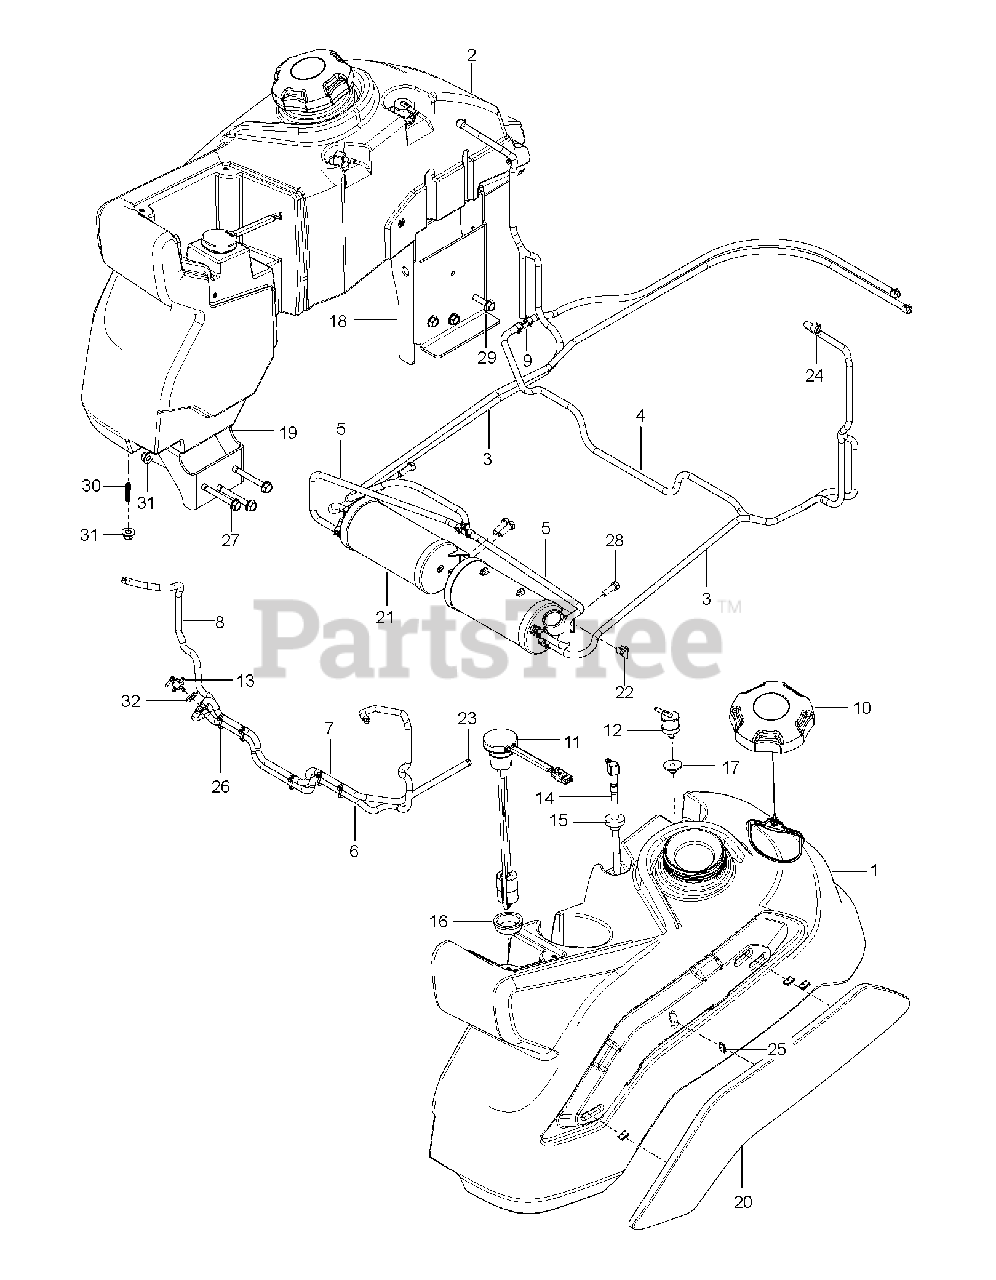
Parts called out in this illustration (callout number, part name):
1	FUEL.TANK.ASM.LH.PZ.REFRESH.18
2	FUEL.TANK.ASM.RH.PZ.REFRESH.18
3	HOSE.3/16".VAPOR.LINE.42"LGTH
4	HOSE.3/16".VAPOR.LINE.55"LGTH
5	HOSE 3/16" VAPOR LINE 13" LENG
6	HOSE.1/4".LOW.PERM.FUEL.LN.46"
7	Fuel Hose, 1/4" Low Perm
8	HOSE.1/4".LOW.PERM.FUEL.LN.24"
9	TEE, FUEL LINE 3/16"
10	CAP, FUEL
11	SENSOR.FUEL.LVL.FLOAT.V500
12	VALVE.FUEL.CHECK
13	FUEL VALVE
14	TUBE.ASM.FUEL.TANK.PICK-UP.LH
15	BUSHING OUTLET T
16	GROMMET, FUEL SENSOR
17	Check Fuel Grommet
18	BRACKET.FUEL.TANK.REAR.SUP.431
19	BRACKET.FUEL.TANK.REAR.SUP.431
20	Fuel Tank Cover, LH Console App
21	CANISTER.FLEX.6.3GAL3/16".TANK
22	1/4-20 U NUT
23	HOSE CLAMP
24	CLAMP, HOSE
25	Clip, U Type
26	TIE WRAP, 8-3/8", W/CLIP
27	BOLT HEX FLGHD 5/16-18X3 GR. 5
28	BOLT
29	SCREW
30	SCREW.5/16-18X1.25"THREADED
31	5/16-18 NYLOC FLANGE NUT
32	WASHER.CLEAR.ZINC
